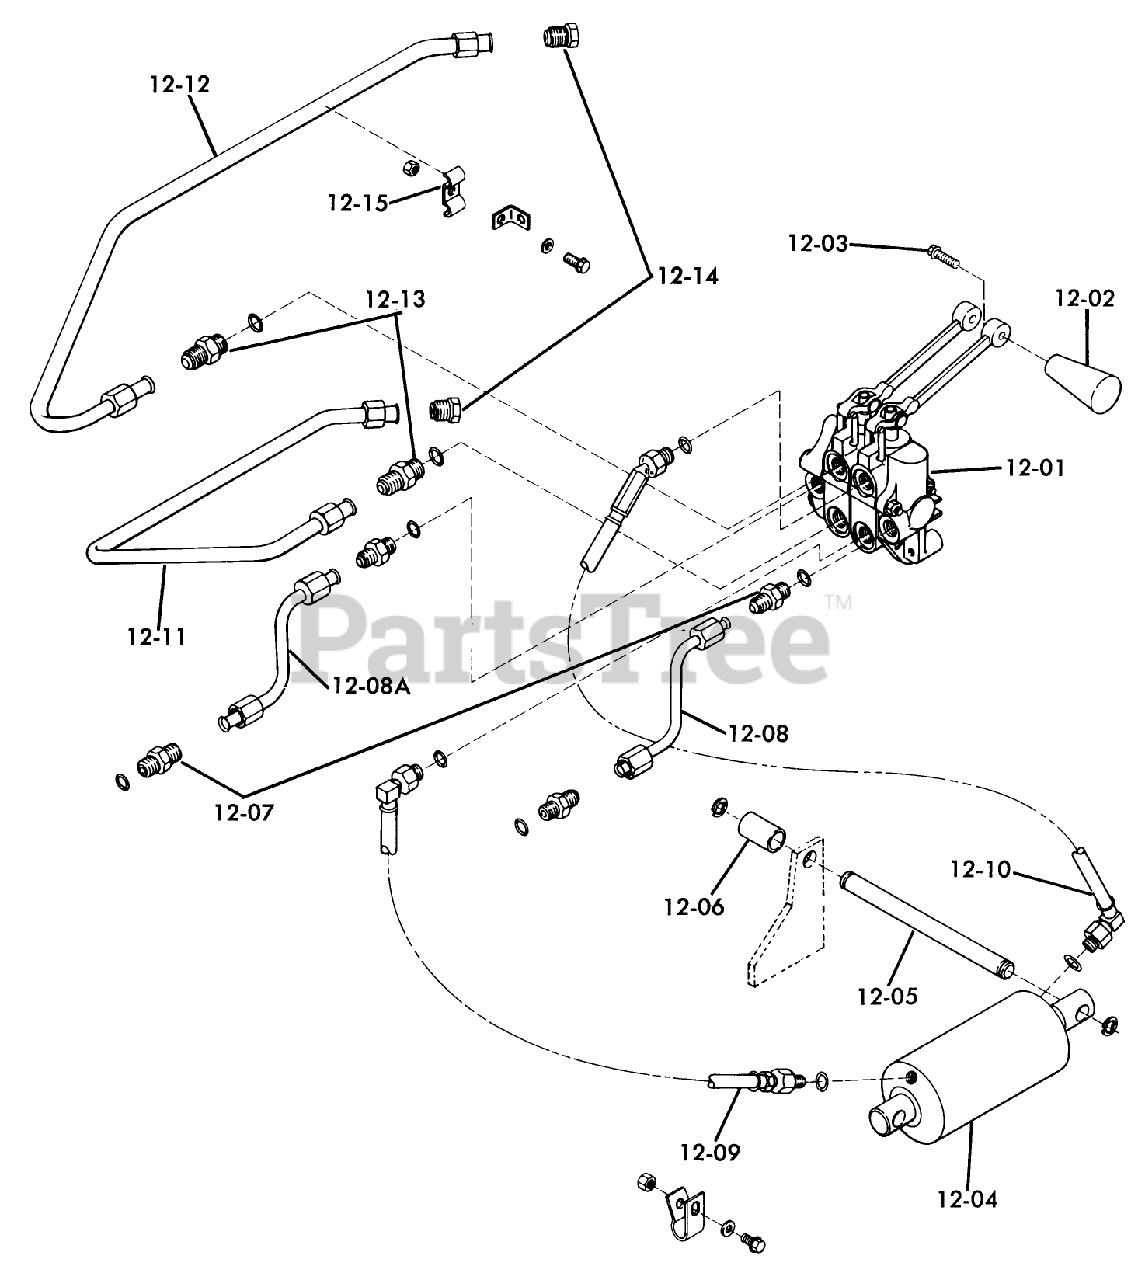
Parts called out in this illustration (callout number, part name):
12-03	SCREW
12-07	FITTING
12-08	PRESSURE TUBE ASSY
12-10	O RING
12-13	O RING
